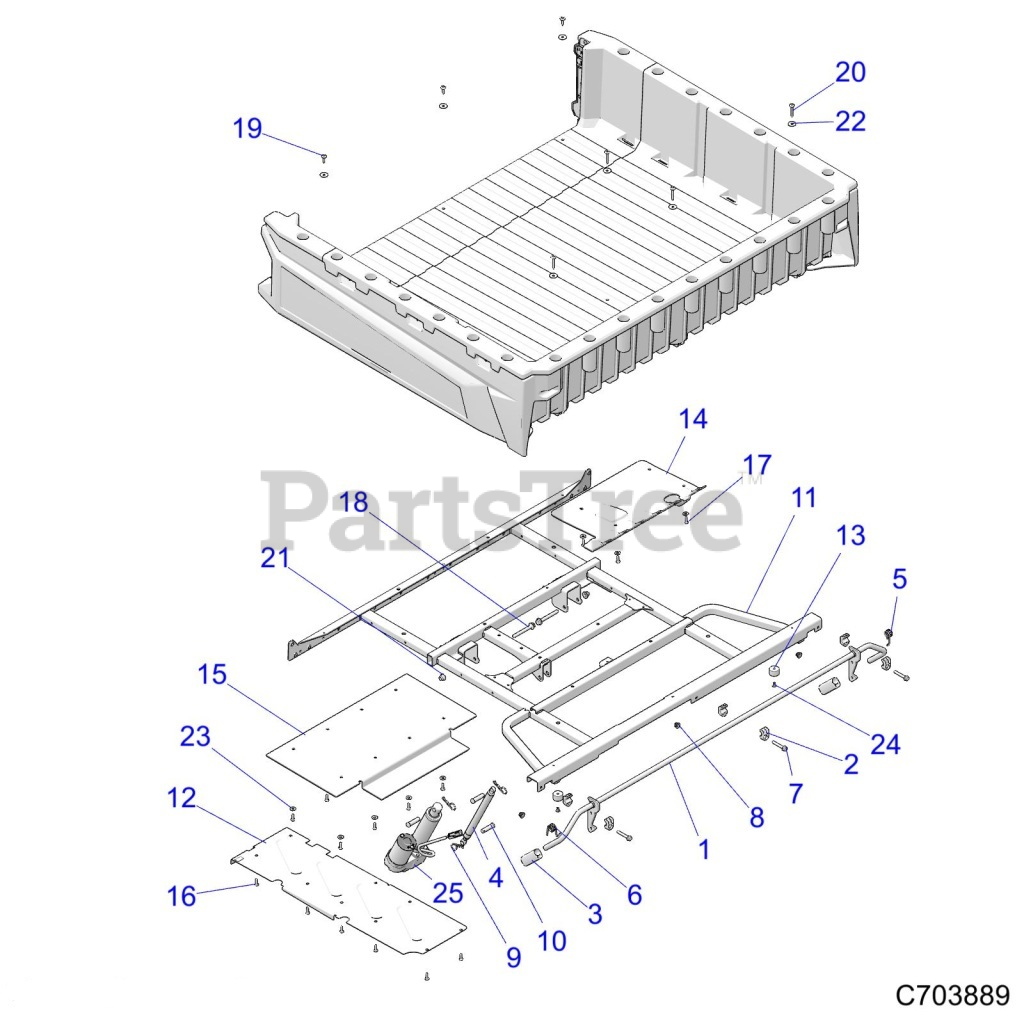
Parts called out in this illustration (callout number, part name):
1	WELD-LATCH,BOX,M.BLK
2	BUSHING-BOX,LATCH
3	HANDLE-BOX, LATCH
4	SHOCK-BOX,DUMP,SM,SINGLE
5	SPRING-LATCH
6	SPRING-LATCH
7	SCR-M8X1.25X50 HX/FL-Y
8	NUT-M8X1.25,HXFLG,NYLON INS
9	CLIP, HITCH PIN
10	PIN, CLEVIS
11	WELD-FRAME,BOX,BLK
12	SHIELD-BOX,CARGO
13	BUMPER-BOX
14	SHIELD-HEAT,FOIL,BOX,RGR
15	SHIELD-HEAT,EXHAUST,REAR
16	SCR-TXPH-#14 X .75 HI-LO RIE
17	SCR-TXPH-#14X3/4 HI/LO CLR
18	SCR-HXFL-M10X1.25X80 8.8 ZOD
19	SCR-TXTH-M6X1.0X25 RIE
20	SCR-TXTH-M6X1.0X45 RIE
21	NUT-M10X1.25,FLG,NYLOC-OLIVE D
22	WASHER-.281X1.00X.051
23	WASHER-.312 X .734 X .065-Z
24	RIVET(50)
25	ACTUATOR,BOX LIFT,CMPT,TTN
